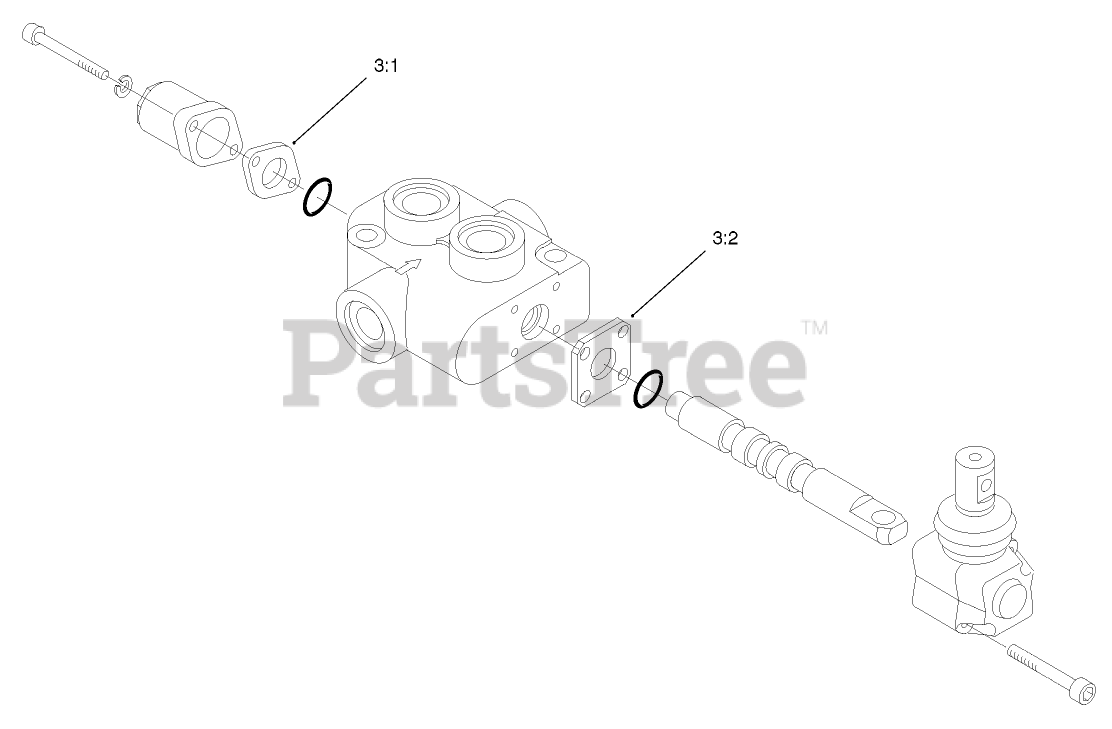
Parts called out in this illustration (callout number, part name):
3	SEAL KIT
3:1	GASKET
3:2	GASKET
